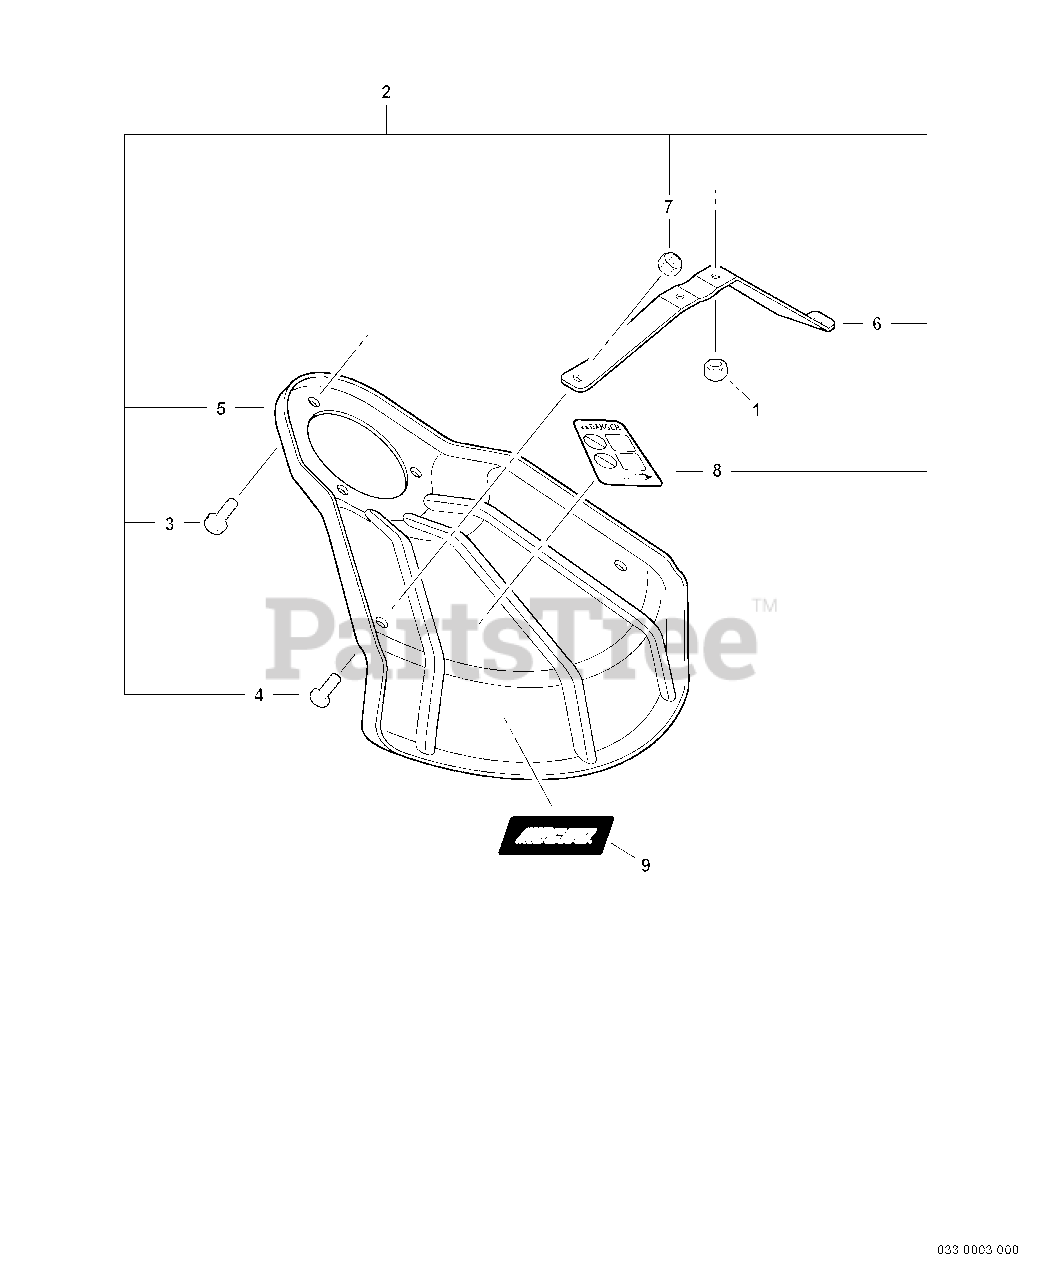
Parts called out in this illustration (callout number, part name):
1	NUT, LOCK M5
2	DEBRIS SHIELD KIT - BLADE
3	SCREW 5×10
4	SCREW 5×8
5	SHIELD, METAL DEBRIS
6	BRACKET, SHIELD MOUNTING
7	NUT, LOCK M5
8	LABEL, DANGER
9	LABEL, ECHO
